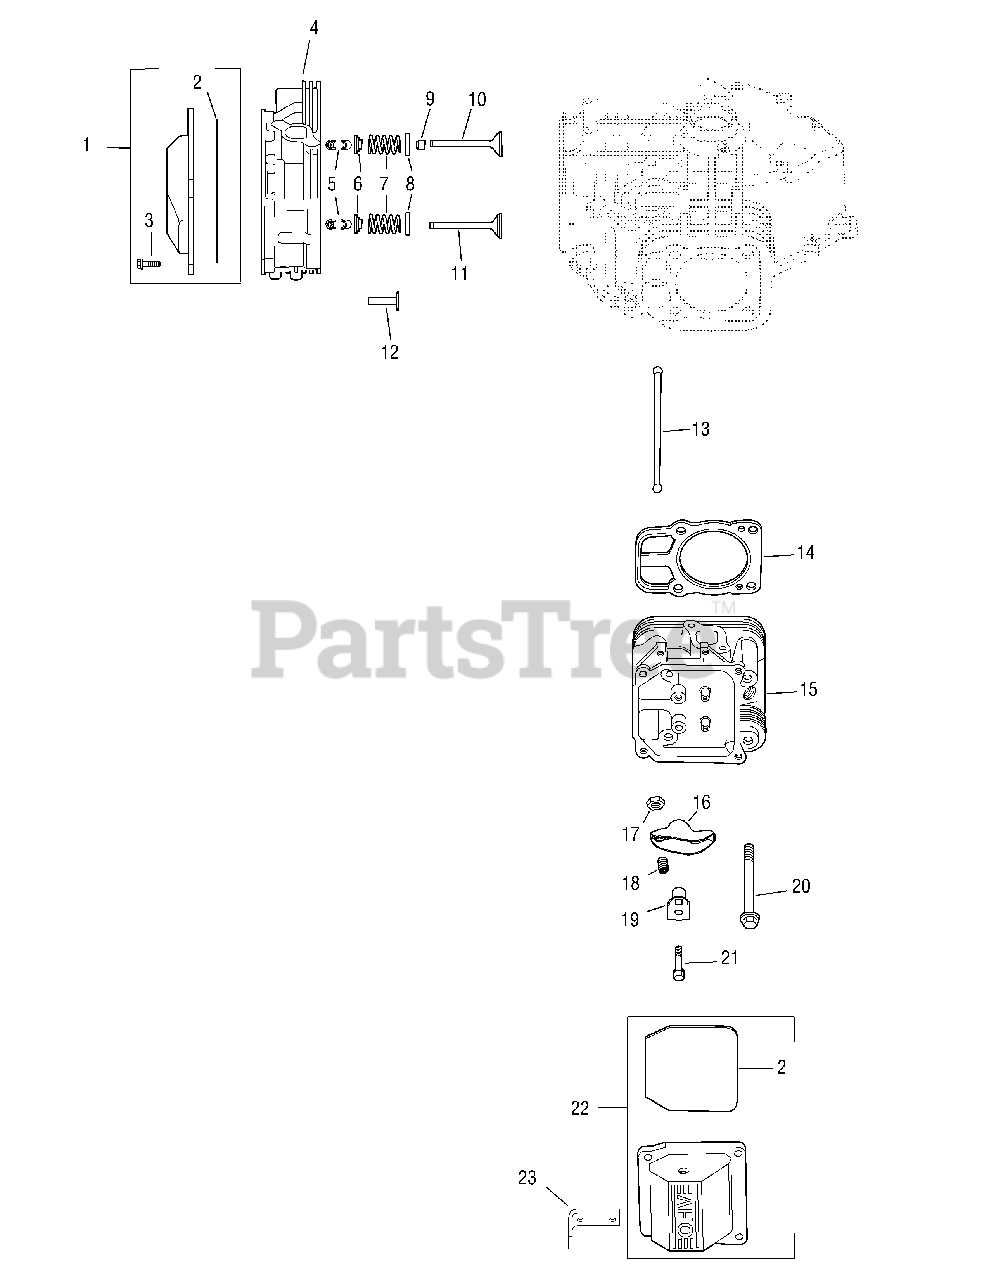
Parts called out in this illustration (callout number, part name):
1	Valve Cover Kit (Inc. 2 & 3)
3	Hex Flange Screw, M6 x 1.0 x 30
4	#1 Cylinder Head Assembly
5	Retainer Kit
6	Valve Spring Cap
7	Valve Spring
8	Spring Retainer
9	Valve Stem Seal
10	Intake Valve (Std.)
10	Intake Valve (.25)
11	Exhaust Valve (Std.)
11	Exhaust Valve (.25)
12	Tappet
13	Push Rod Cylinder Head Gasket Kit (Inc. Head
14	Mounting Hardware & KH-24-041-49-S & KH-24-153-27-S)
15	#2 Cylinder Head Assembly
16	Rocker Arm
17	Hex Nut, M10 x 0.75
19	Rocker Arm Pivot
20	Hex Flange Screw, M10 x 1.5 x 90
21	Hex Flange Screw, M6 x 1.0 x 45
22	Valve Cover Kit - Breather (Inc. 2)
23	Lifting Strap
